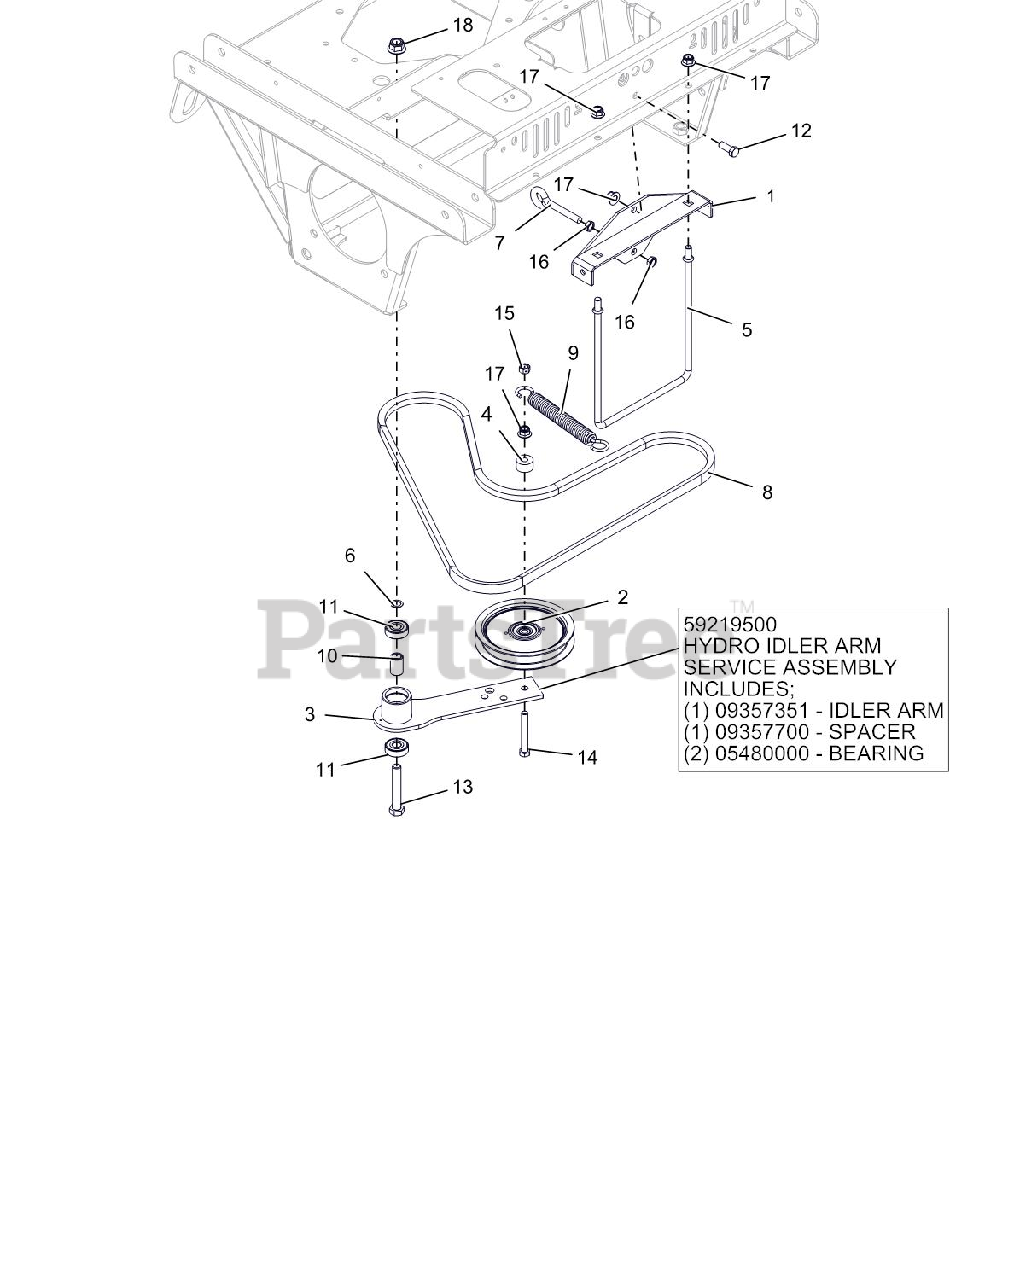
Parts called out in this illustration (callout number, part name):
1	SPRING ANCHOR BRKT WMT - BLACK
2	IDLER, FLAT-5.00X.75
3	BRG-BALL .50X1.38X.438 SEALED
3	SPACER .510 X .75 X 1.1485
3	KIT, HYDRO IDLER ARM PT200/400
3	HYDRO DRIVE IDLER ARM WMT- BLK
4	SPACER .390X1.000X.562
5	ROD, BRAKE MTG
6	WASHER, .500X.750X.020 THRUST
7	BLT-EYE .375-16X2.50 YWZC
8	V-BELT, COGGED B-RAW EDGE
9	SPRING, EXTENSION
10	SPACER .510 X .75 X 1.1485
11	BRG-BALL .500X1.38X.437
12	@BLT-HEX .38-16X1.00 GR5 YWZC
13	@BLT-HEX .50-13X3.00 GR5 YWZC
14	@BLT-HEX .38-16X2.75 GR5 YWZC
15	@NUT-LK-CTR .38-16 YWZC
16	NUT-HEX-JAM .375-16 YWZC
17	@NUT-LK-NYL-FLG .38-16 YWZC
18	@NUT-LK-NYL-FLG .50-13 YWZC
